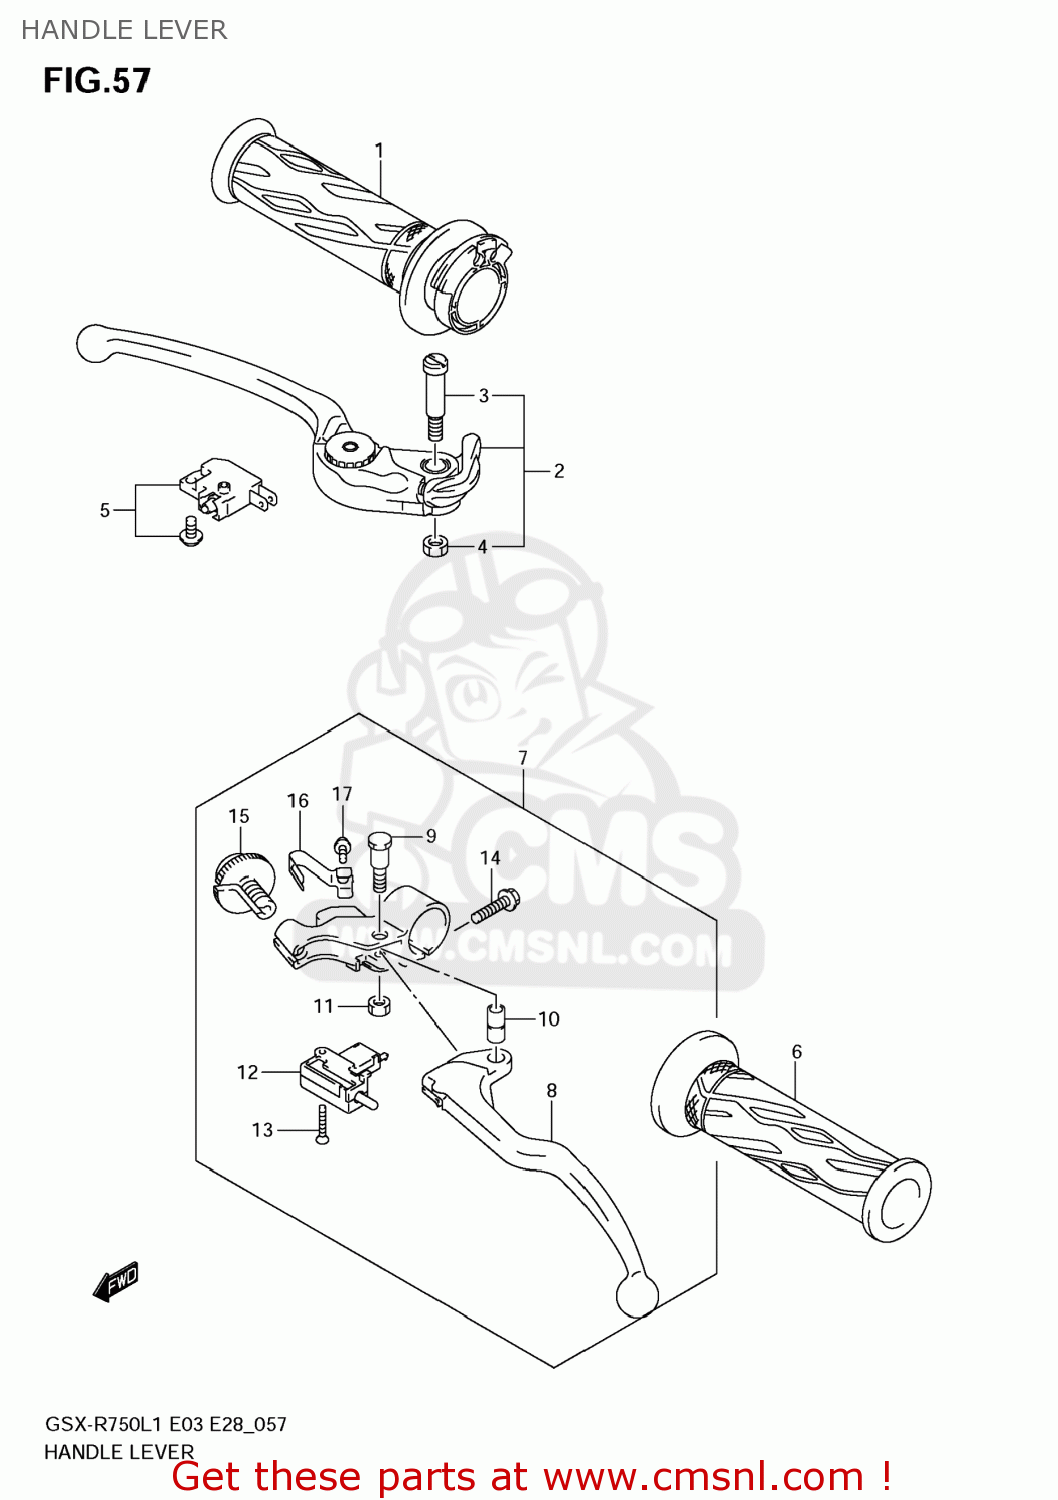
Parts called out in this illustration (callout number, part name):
1	GRIP,THROTTLE
2	LEVER ASSY,BRAKE
3	BOLT,LEVER PIVOT
4	NUT,LEVER PIVOT
5	SWITCH ASSY,FR
6	GRIP,L
7	LEVER ASSY,CLUTCH
8	LEVER,CLUTCH
9	BOLT,CLUTCH LEVER PIVOT
10	COLLAR
11	NUT
12	SWITCH,CLUTCH
13	SCREW
14	BOLT
15	NUT,ADJUSTER
16	SPRING,ADJUST
17	SCREW,SPRING
